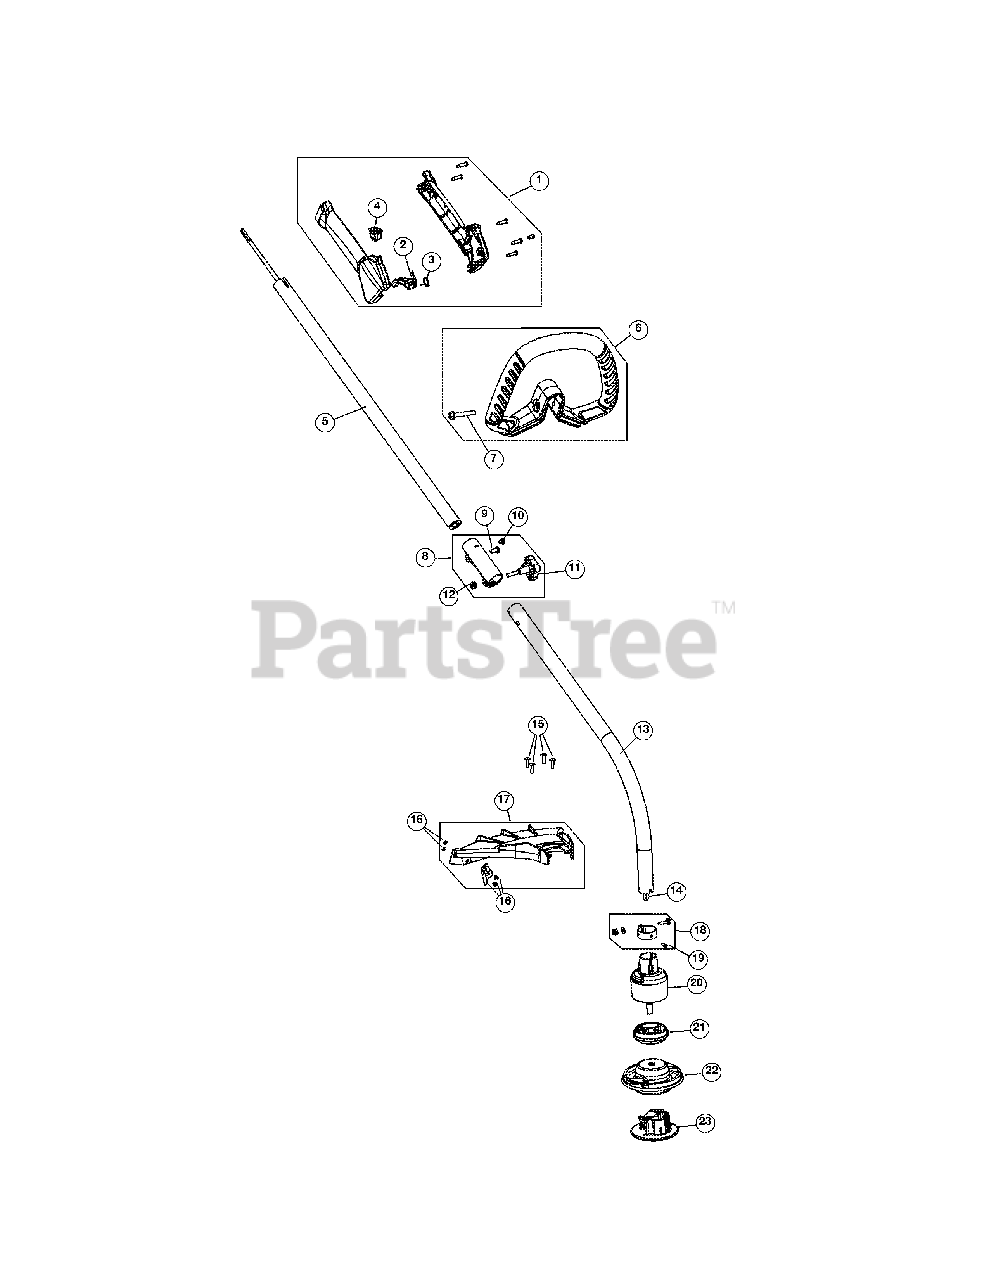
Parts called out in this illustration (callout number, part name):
1	Throttle Housing Assembly (Incl Ref No. 2-4)
2	Throttle Trigger
3	Throttle Trigger Spring
4	Switch Assembly
5	Upper Drive Shaft Housing
6	Deluxe D-Handle Assembly (Incl Ref No. 7)
7	Handle Bolt
8	Split Boom Coupler (Incl Ref No. 9-12)
10	Anti-Rotation Screw
11	Adjustment Knob (Incl Ref No. 12)
13	Lower Drive Shaft Housing (Incl Ref No. 14)
14	Lower Flexible Drive Shaft
15	Shield Mount Hardware
16	Blade Assembly
17	Shield Assembly (Incl Ref No. 16)
18	Lower Clamp Assembly (Incl Ref No. 19)
19	Anti-Rotation Screw
20	Bushing Housing Assembly
21	Adapter
22	Cutting Head Assembly
23	Glide Plate
